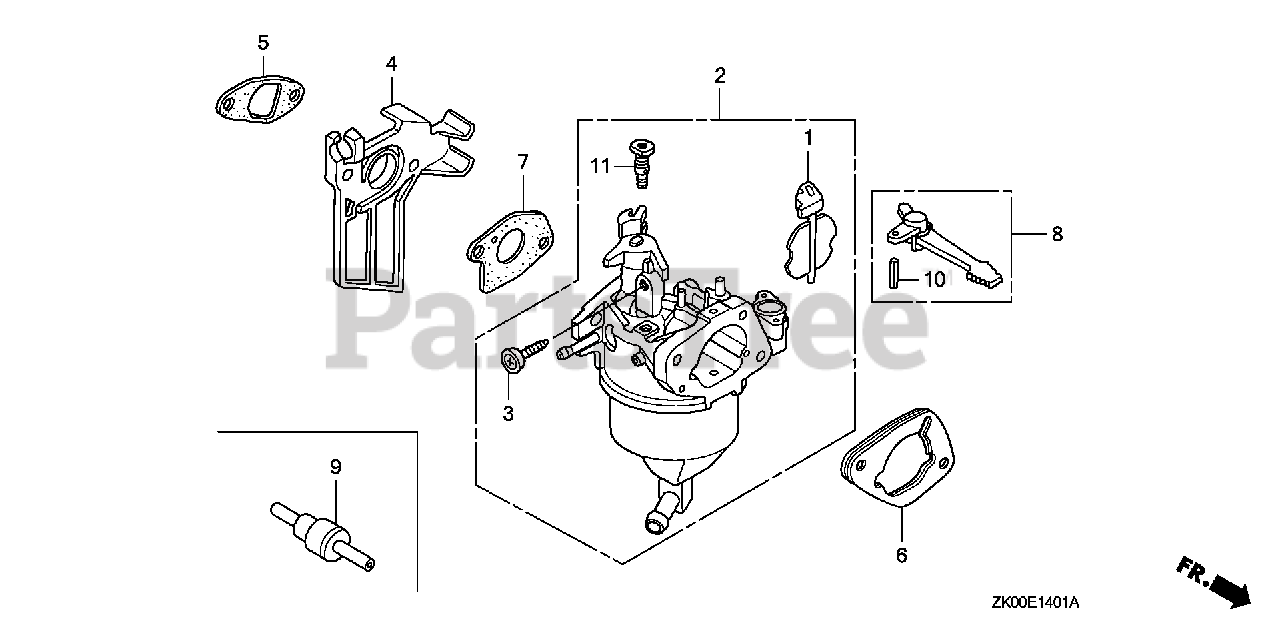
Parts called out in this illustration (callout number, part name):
2	CARBURETOR ASSY. (BEL1A A)
3	SCREW, THROTTLE STOP
4	INSULATOR, CARBURETOR
5	GASKET, INSULATOR
6	SPACER, CARBURETOR
7	GASKET, CARBURETOR
8	LEVER, CHOKE (STD)
9	VALVE, DASHPOT CHECK
10	PIN, SPRING (2X12)
11	JET, PILOT (#35)
